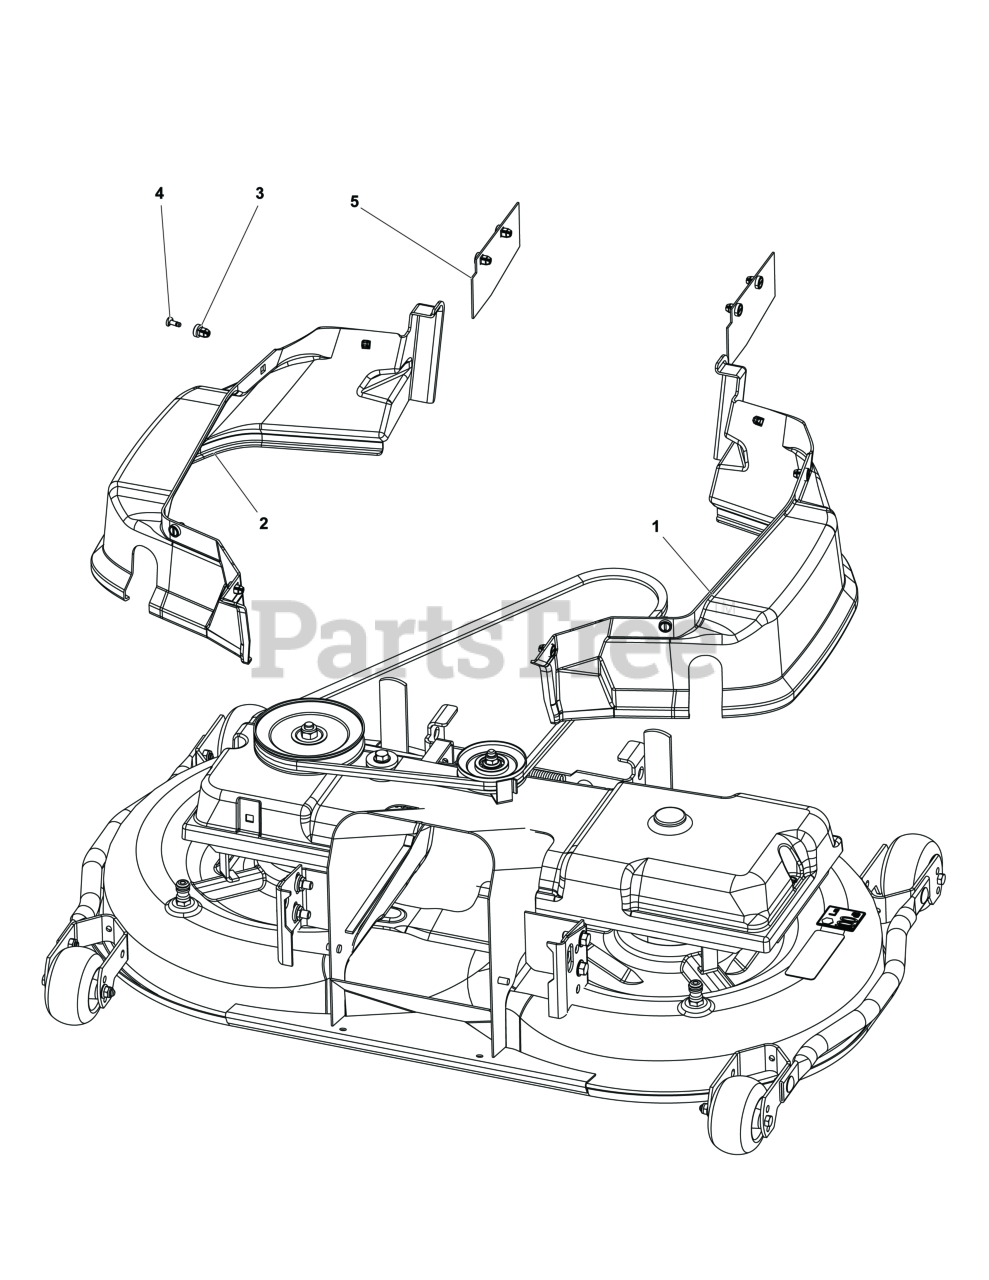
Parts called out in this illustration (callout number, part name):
1	COVER, Belt
2	COVER, Belt
5	COVER, Clutch
